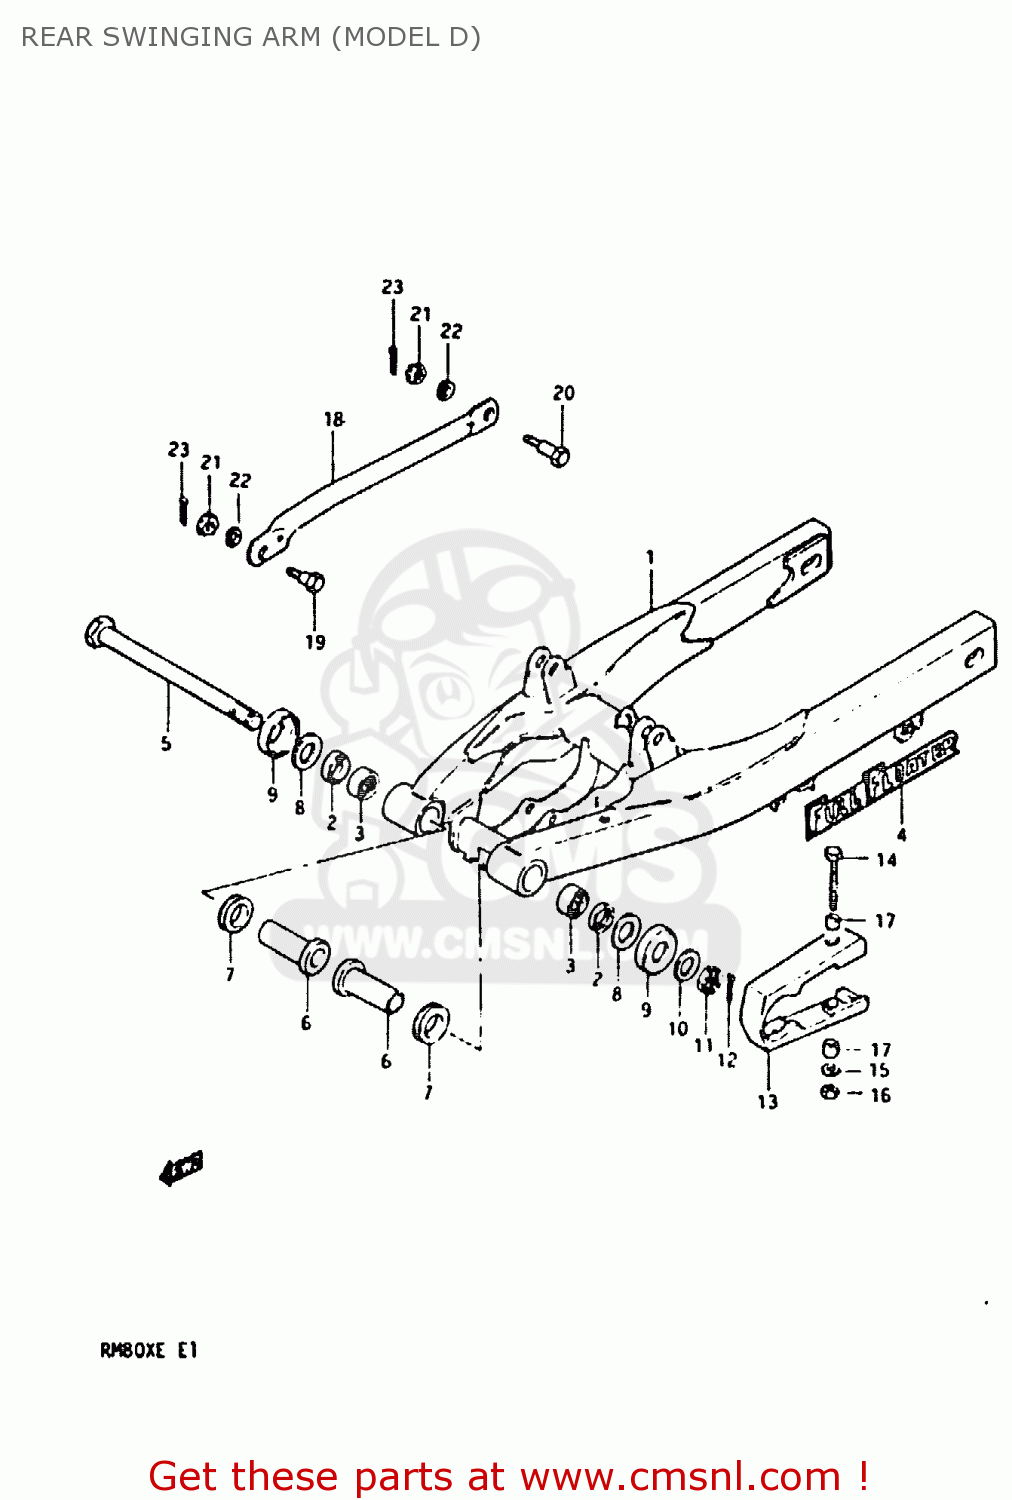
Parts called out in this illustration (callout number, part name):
1	SWING ARM ASSEMBLY,REAR
2	SEAL,OIL(17X24X3)
3	ROLLER BEARING (17X24X2
4	EMBLEM,SWING ARM
5	SHAFT,REAR SWING ARM
6	SPACER,RR SWGARM PIVOT
7	SEAL,OIL(17X24X5)
8	WASHER
9	COVER,RR SWGARM DUST SEAL
10	WASHER
11	NUT, REAR AXLE
12	COTTER PIN
13	BUFFER,CHAIN TOUCH DEFLECTOR
14	SCREW,CHAIN TOUCH DEFEND
15	WASHER
16	NUT
17	SPACER (5.5X8X4)
18	LINK,REAR TORQUE
19	BOLT(8X22)
20	BOLT(8X21)
21	NUT
22	LOCK WASHER
23	PIN 20X20
